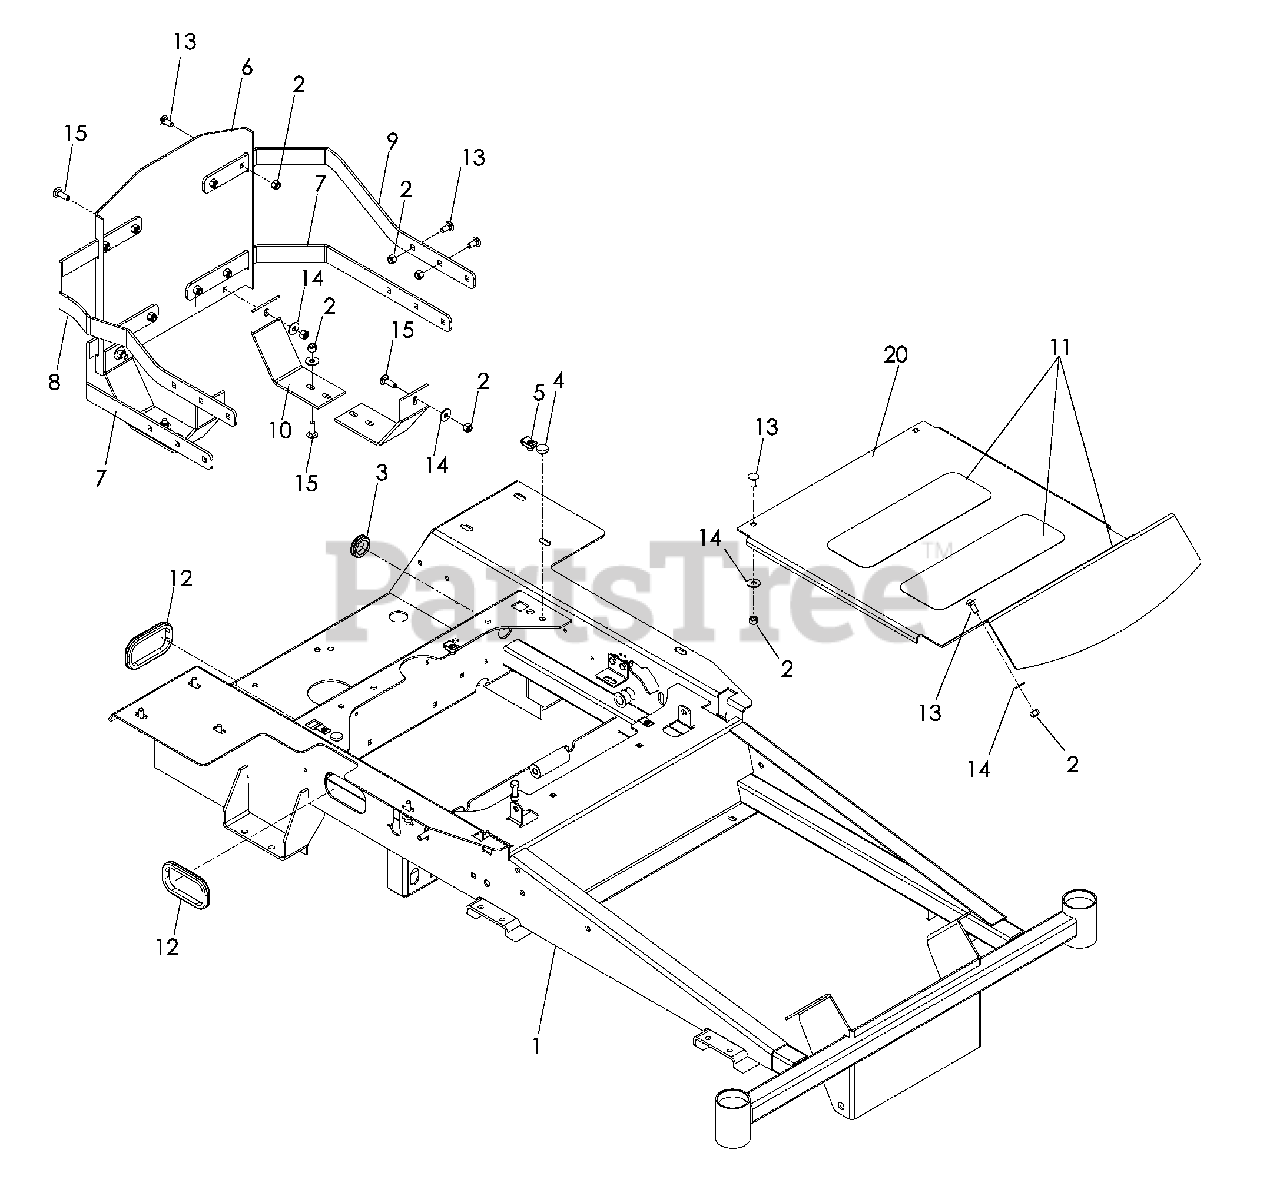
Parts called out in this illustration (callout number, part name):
1	FRAME W/DECALS All Models Before Serial No. 0749Xxxxx
2	NUT 5/16-18 NYLOC
3	RUBBER GROMMET
4	GROMMET, BUMPER
5	NUT 5/16-18 RETAINER-U
6	ENGINE GUARD
7	LOWER GUARD
8	UPPER RT HAND GUARD
9	UPPER LT HAND GUARD
10	SKID PLATE
11	PAD, ABRASIVE
13	RHSNB 5/16-18 x ¾
14	WASHER 5/16
15	RHSNB 5/16-18 x 1
16	PAN, FLOOR
